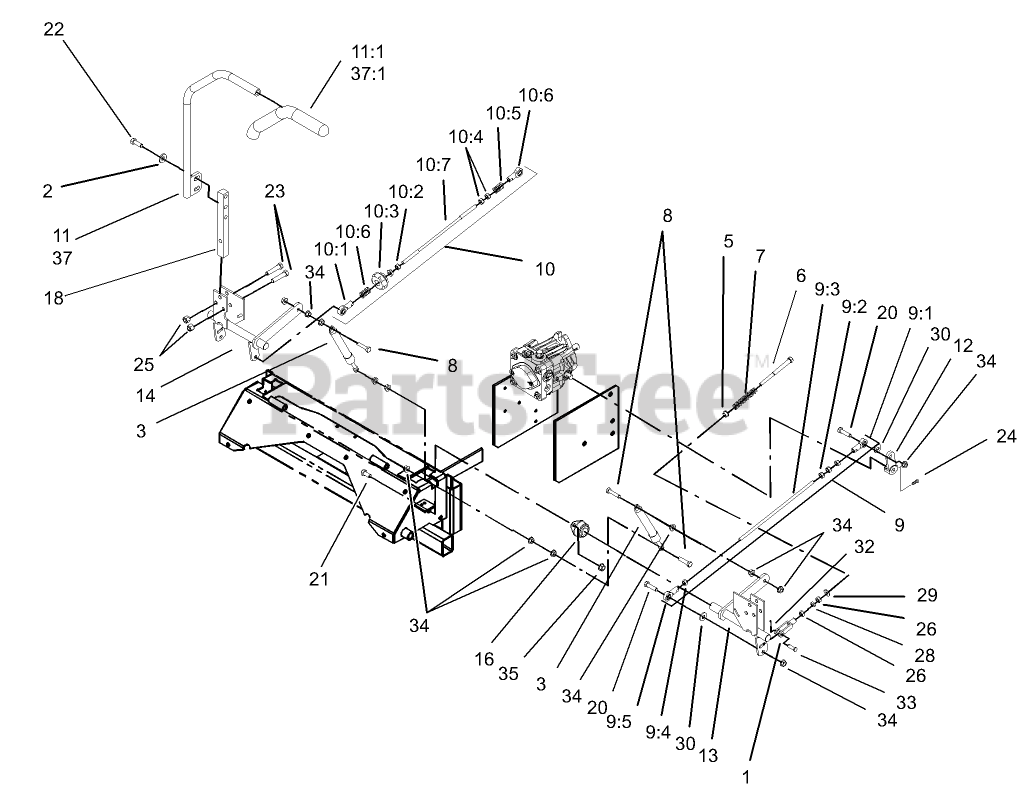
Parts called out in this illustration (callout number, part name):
1	YOKE-ADJUSTABLE
2	WASHER-BELLEVILLE
3	Damper-Control, Motion
5	BUSHING-FLANGED
6	BOLT-RETURN, NEUTRAL
7	SPRING-RETURN, NEUTRAL
8	SCREW-HH
9	LH Pump Linkage ASM
9:1	BALLJOINT-RH
9:2	NUT-HEX
9:3	Link-Rod, Tracking
9:5	BALLJOINT-LH
10	Tracking Rod ASM
10:1	BALLJOINT-RH
10:2	NUT-HEX
10:3	KNOB-TRACKING
10:5	SPRING-COMPRESSION
10:6	BALLJOINT-LH
10:7	Link-Rod, Tracking
11	RH LEVER ASM
11:1	GRIP-CONTROL, MOTION
12	ARM-CONTROL, PUMP
13	CONTROL-MOTION, LH
14	CONTROL-MOTION, RH
16	BEARING-FLANGE, SIDE
18	ARM-SHAFT, CONTROL
20	SCREW-HH
21	SCREW-HH
22	SCREW-HH
23	SCREW-HH
24	SCREW-SET
25	NUT-LOCK, NI
26	NUT-HEX
28	NUT-JAM
29	WASHER-FLAT
30	WASHER-FLAT
32	PIN-COTTER
33	PIN-CLEVIS
34	NUT-HF
35	NUT-HHF, WHIZ
37	LH LEVER ASM
37:1	GRIP-CONTROL, MOTION
